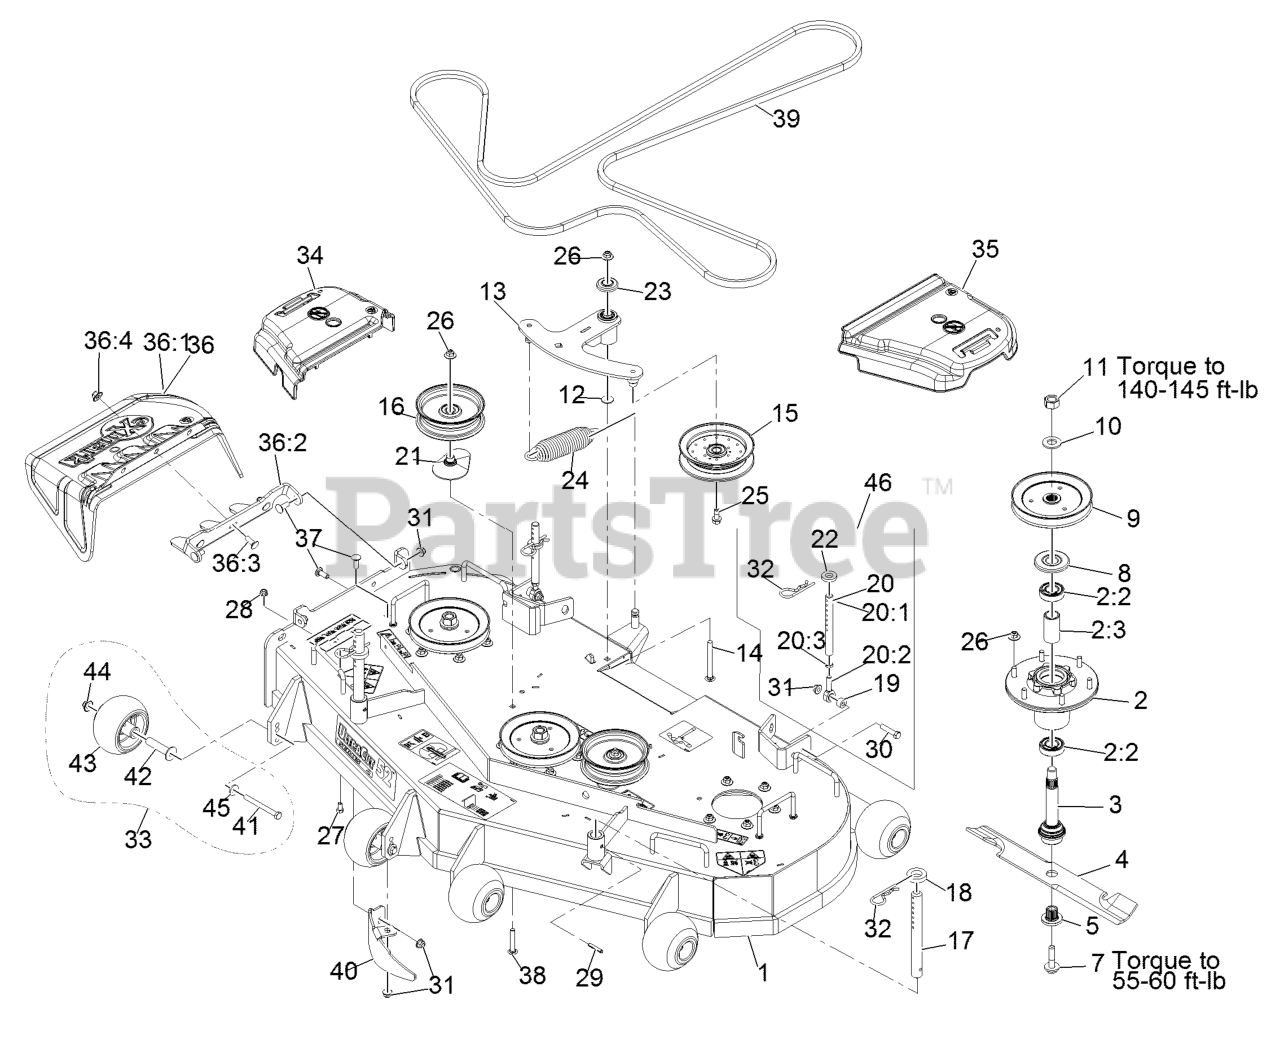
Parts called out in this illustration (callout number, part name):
1	ASM, DECK W/ DECALS, 52"
2	ASM-CUTTER HSG WITH BEARINGS
2:2	BEARING-BALL
2:3	SPACER-BEARING
3	ASM-SPINDLE AND SEAL
5	BUSHING,SPLINED
7	SCREW,SEMS 1/2-20 X 2.19
8	GUARD,BEARING TOP .989
9	SHEAVE,BLADE DRIVE 6.50
11	NUT-HEX
12	WASHER-FLAT
13	ASM, DECK IDLER
14	SCREW-CARR
16	IDLER-PULLEY, FLAT
17	ROD,DECK SUPPORT
18	SPACER-DECK SUPPORT
20:1	LINK,SUPPORT
20:2	BALLJOINT
20:3	NUT-HJ
21	SPACER-PULLEY
23	GUARD-TOP
24	SPRING-EXTENSION
25	SCREW-HFH
26	Nut-Nyloc 3/8-16 Flg
27	SCREW-HH
28	NUT-HF, NI
30	SCREW-HH
31	NUT-HF, NI
32	PIN,HAIR COTTER
33	KIT, ANTI-SCALP ROLLER
34	COVER-BELT, RH
35	COVER-BELT, LH
36	ASM,DISCHARGE CHUTE
36:1	CHUTE,DISCHARGE
36:2	BRACKET,DISCHARGE CHUTE
36:3	SCREW-CARR
36:4	Nut-Nyloc 3/8-16 Flg
37	SCREW-CARR
38	BOLT-CARR, SHORT NECK
39	BELT, DECK DRIVE
40	BAFFLE-DOGLEG, LZ-VT52
41	SCREW-HH 3/8-16 X 3 3/4 GR 8
42	AXLE, ROLLER
43	ROLLER-SCALP, ANTI
44	Nut-Nyloc 3/8-16 Flg
45	WASHER-BELLEVILLE
46	KIT,SUPPORT LINK W/PIN
